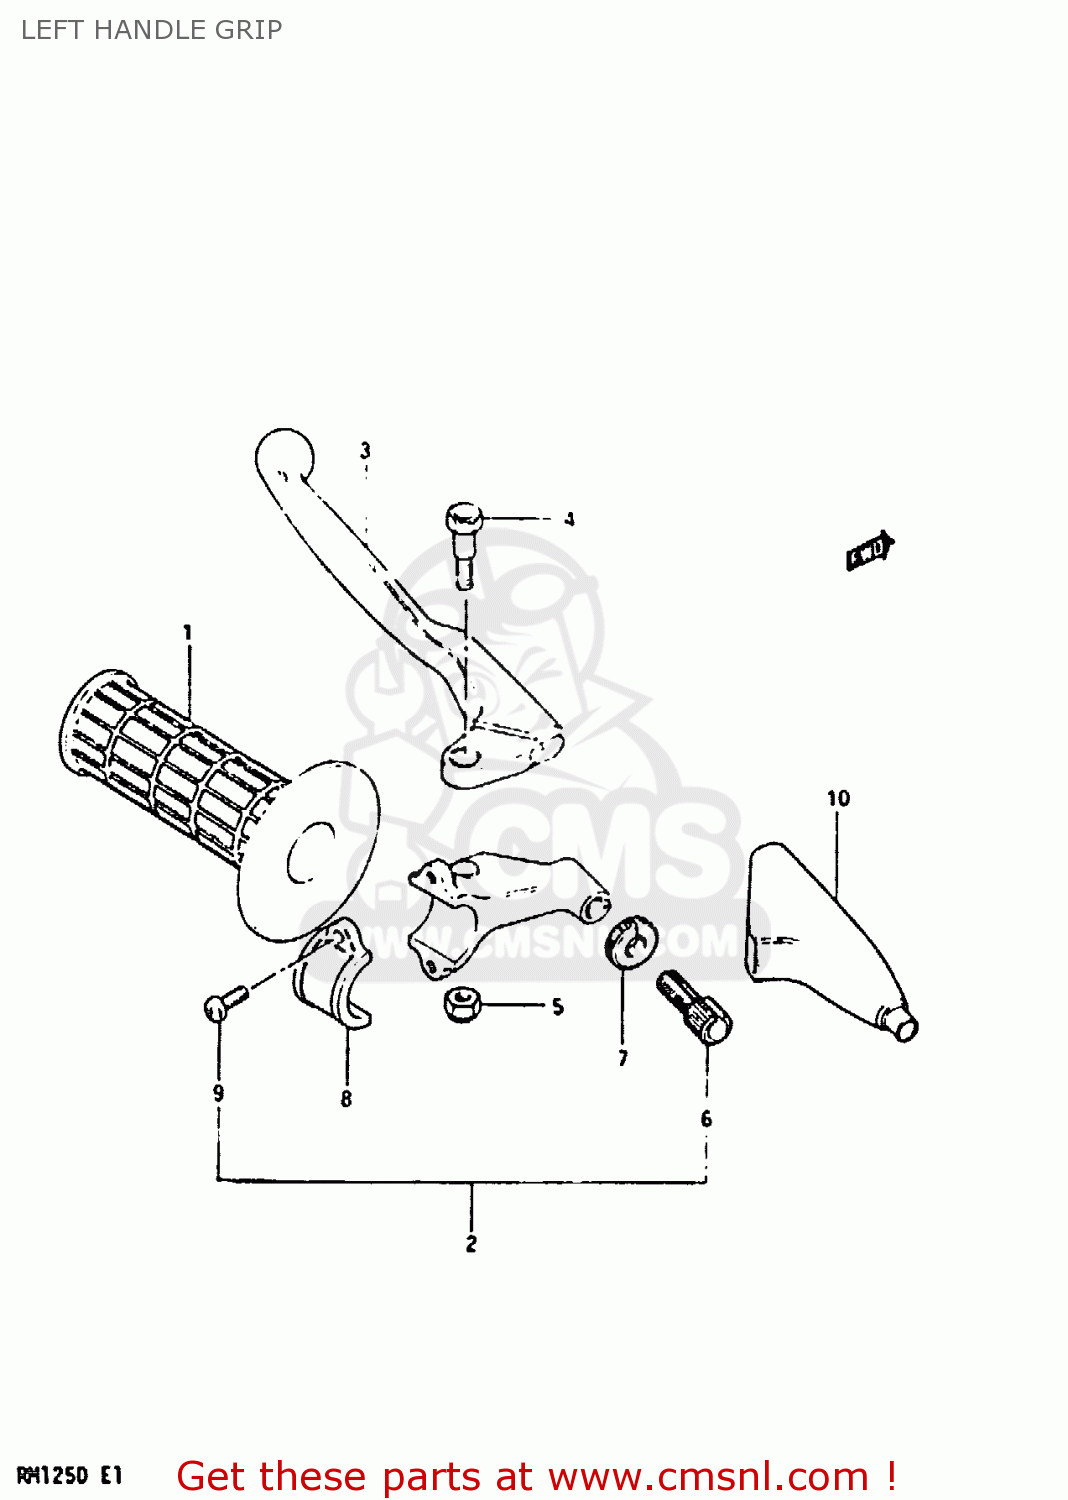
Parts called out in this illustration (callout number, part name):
1	GRIP,LEFT
2	LEVER ASSY,CLUTCH
3	LEVER,CLUTCH
4	BOLT,LEVER
5	NUT 6MM
6	ADJUSTER,CABLE
7	NUT,CABLE ADJUSTER
8	BRACKET,CLUTCH LEVER HOLDER
9	SCREW
10	COVER,CLUTCH LEVER
